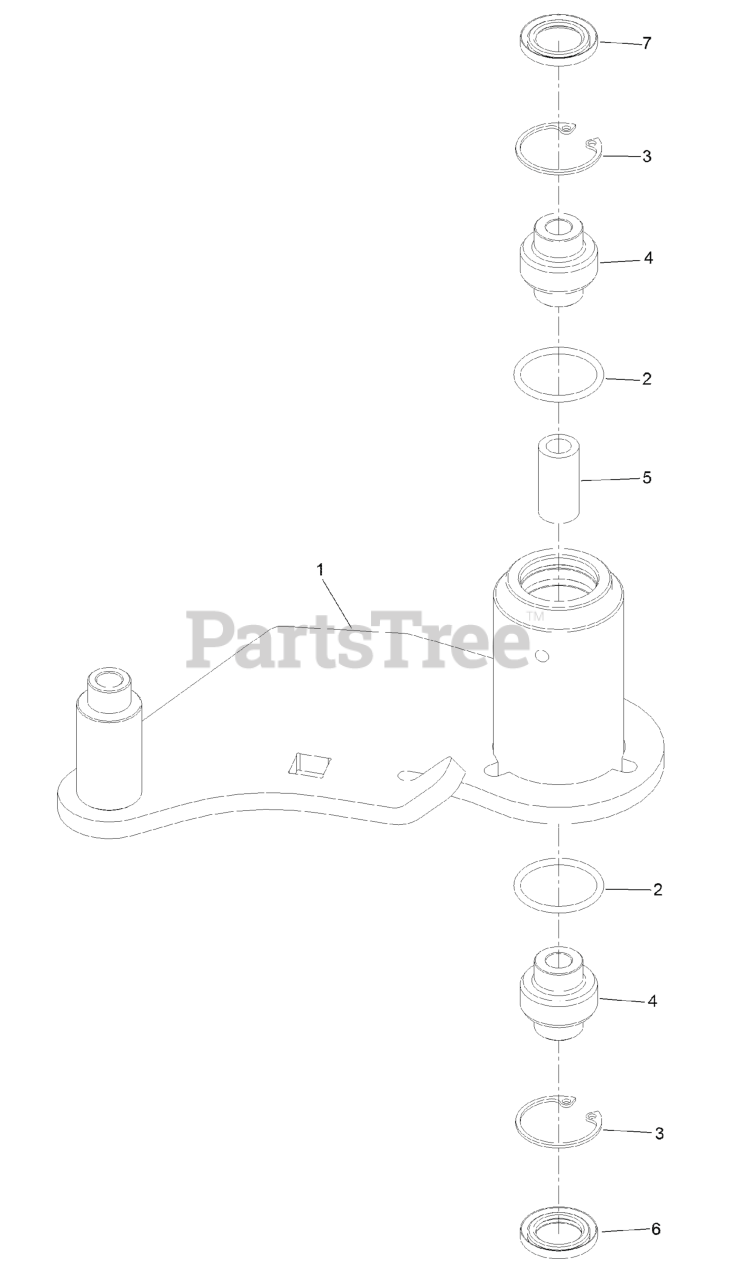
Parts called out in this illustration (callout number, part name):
1	Idler-Deck
3	RING-SNAP
4	BEARING-SPHERICAL
6	SEAL-LIP, DOUBLE
7	SEAL-LIP, SINGLE
